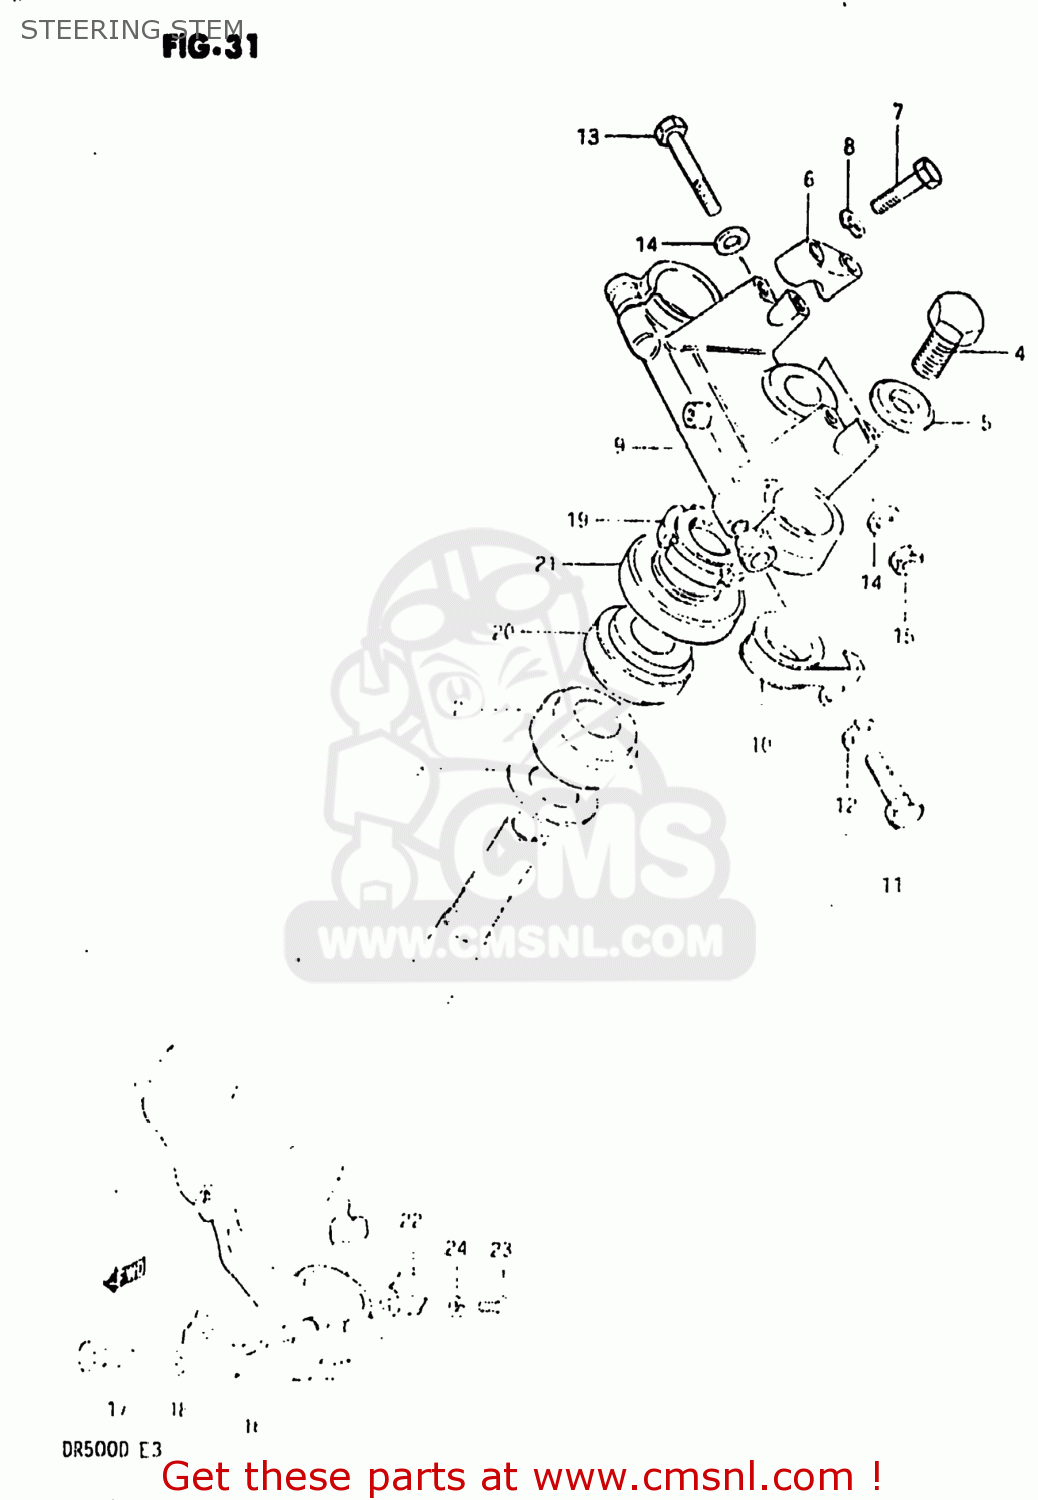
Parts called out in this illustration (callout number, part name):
1	STEM,STEERING
2	BEARING
3	WASHER,THRUST
4	BOLT
5	WASHER
6	HOLDER,HANDLEBAR
7	BOLT
8	LOCK WASHER
9	HEAD,STEERING STEM
10	GUIDE,CABLE
11	BOLT
12	LOCK WASHER
13	BOLT 8X50
14	WASHER
15	NUT
16	GUIDE,CABLE
17	BOLT 8X45
18	LOCK WASHER
19	NUT,STEERING STEM(25X44X10)
20	TAPER,ROLLER BEARING
21	DUST SEAL,STEERING UPR
22	CLIP,BRAKE CABLE
23	SCREW
24	LOCK WASHER
